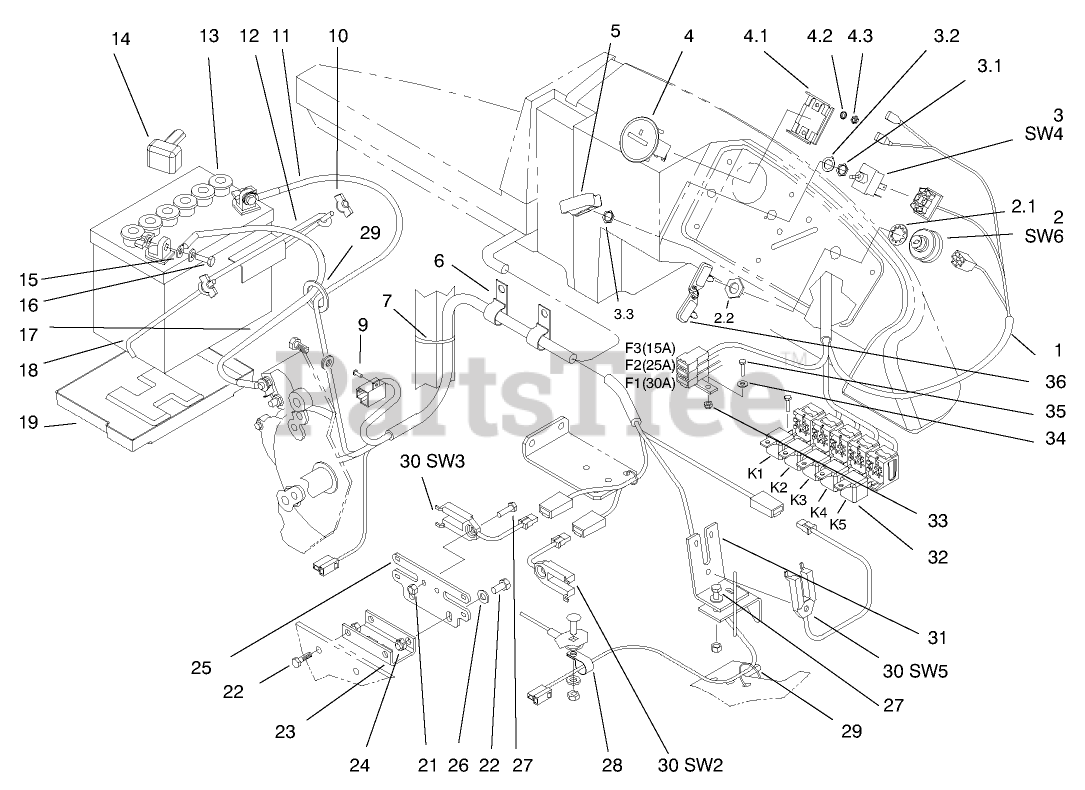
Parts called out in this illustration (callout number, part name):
1	HARNESS
2	IGNITION SWITCH ASM
2.2	WASHER-LOCK
3	SWITCH-TOGGLE, SEALED
3.1	NUT-HEX, SPECIAL
3.2	TAB-WASHER
4	Hourmeter
4.1	CLAMP-HOUR METER
4.2	WASHER-LOCK
4.3	NUT-HEX
5	COVER-PTO SWITCH
6	CLAMP-J
7	TIE-CABLE
9	SCREW-TAP
10	NUT-WING
11	WIRE ASM (NEGATIVE)
12	HOLDDOWN-BATTERY
13	Battery
14	BOOT-TERMINAL
15	WASHER-FLAT
16	SCREW-HH
17	WIRE ASM
18	RETAINER-BATTERY
19	TRAY-BATTERY
21	NUT-LOCK, NI
22	SCREW-HH
23	CHANNEL-MOUNT, SWITCH
24	NUT-LOCK, NI
25	PLATE-MOUNT, SWITCH
26	WASHER-PLAIN
27	SCREW-HH
28	CLAMP-R
29	TIE-CABLE
30	SWITCH-INTERRUPTER
31	ANGLE - MOUNT,SWITCH
32	RELAY
33	NUT-LOCK, NI
34	WASHER-FLAT
35	SCREW-HWH
36	KEY-IGNITION
39	JUMPER
